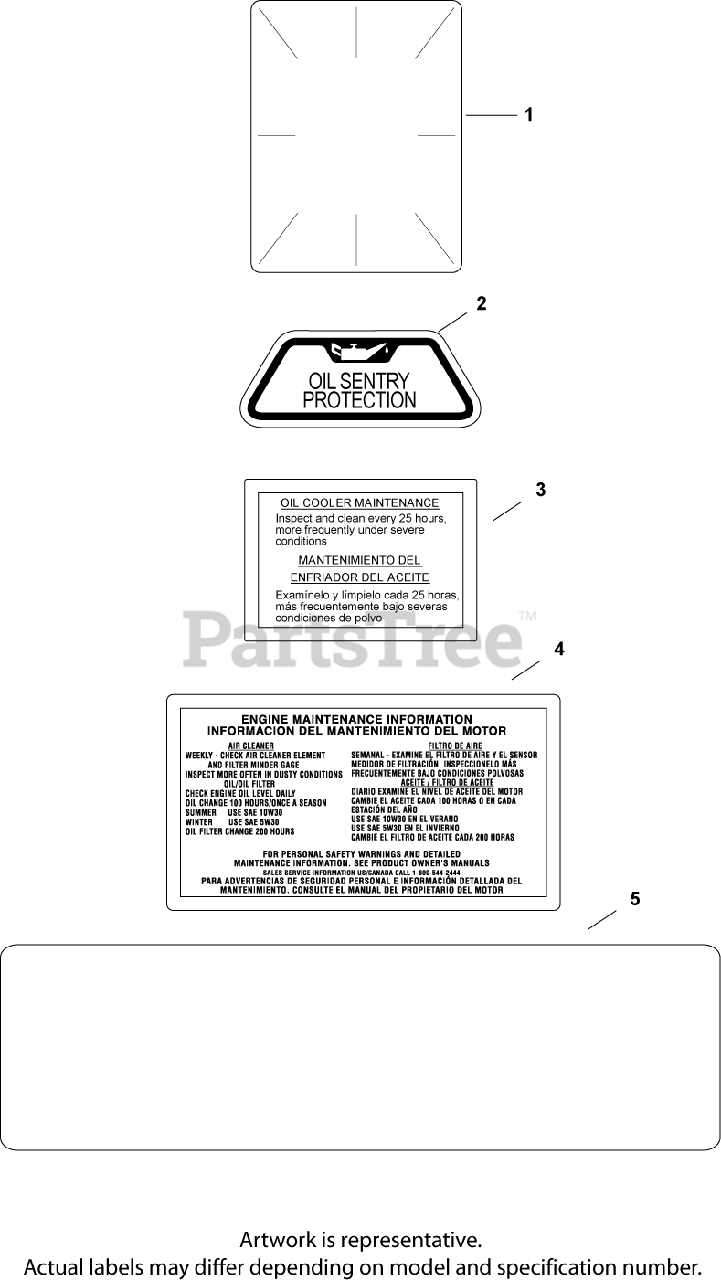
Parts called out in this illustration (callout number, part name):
1	DECAL, CLEAR LAMINATE USE 25 113 70-S
2	DECAL, OIL SENTRY - (#DSC)
3	DECAL, OIL COOLER MAINTENANCE-DISC.
4	DECAL, ENGINE MAINTENANCE - DISC.
5	DECAL, 30 HP - DISCONTINUED
